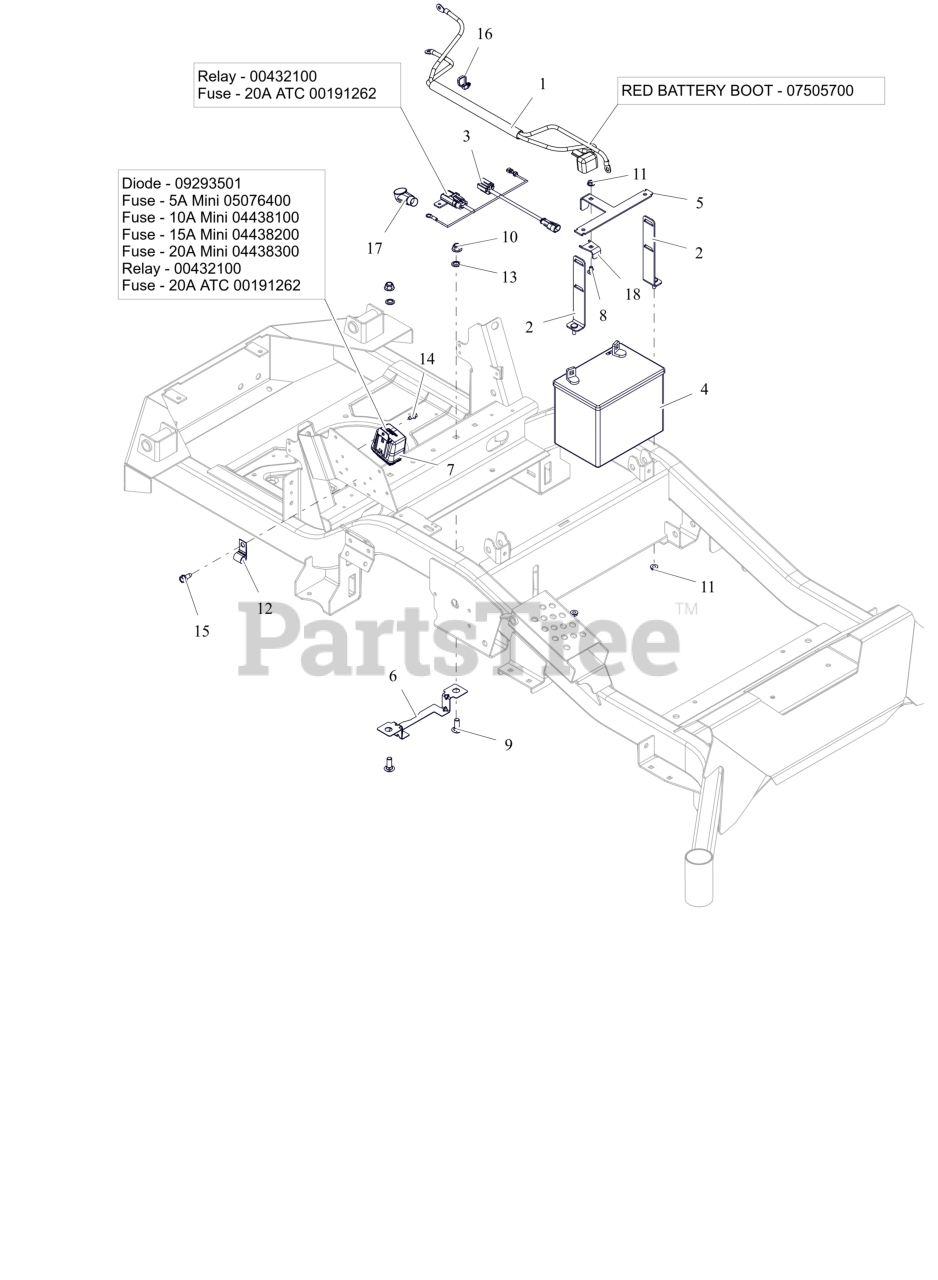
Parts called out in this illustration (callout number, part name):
1	HARNESS, BATTERY HD
1	INSULATOR
2	WMT,BATTERY MOUNT HOLD DOWN
3	HARNESS, STARTER ADAPTOR
3	RELAY,SEALED W/DIODE
3	FUSE, 20 AMP BLADE S/O
4	BATTERY, 300 CCA 10U1L
5	BRKT, BATTERY TIE DOWN
6	GUARD, ELECTRICAL HARNESS
7	HARNESS, WIRE
7	FUSE, 5 AMP MINI-ATC
7	FUSE,10 AMP MINI-ATC
7	Fuse, 15 AMP MINI-ATC
7	FUSE,20 AMP MINI ATC
7	RELAY,SEALED W/DIODE
7	FUSE, 20 AMP BLADE S/O
8	BLT, RHSN .25-20X.500 G5 ZCC
9	BLT, RHSN .38-16X1.00 G5 ZCC
10	NUT,NYL-FLG .38-16 GF ZCC
11	NUT-LK-TOP-FLG .250-20 GF ZCC
12	J-CLAMP
13	NUT-PUSH .38 DIA. PAL ZINC
14	SCR-TAP .25-20X.50 HWH ZCC
15	SCR,TAP .312-18X.75 HWH TR ZCC
16	CABLE TIE W/ TREE (.25 HOLE)
17	BOOT, .65ID POS
18	BRKT, BATTERY HOLD
